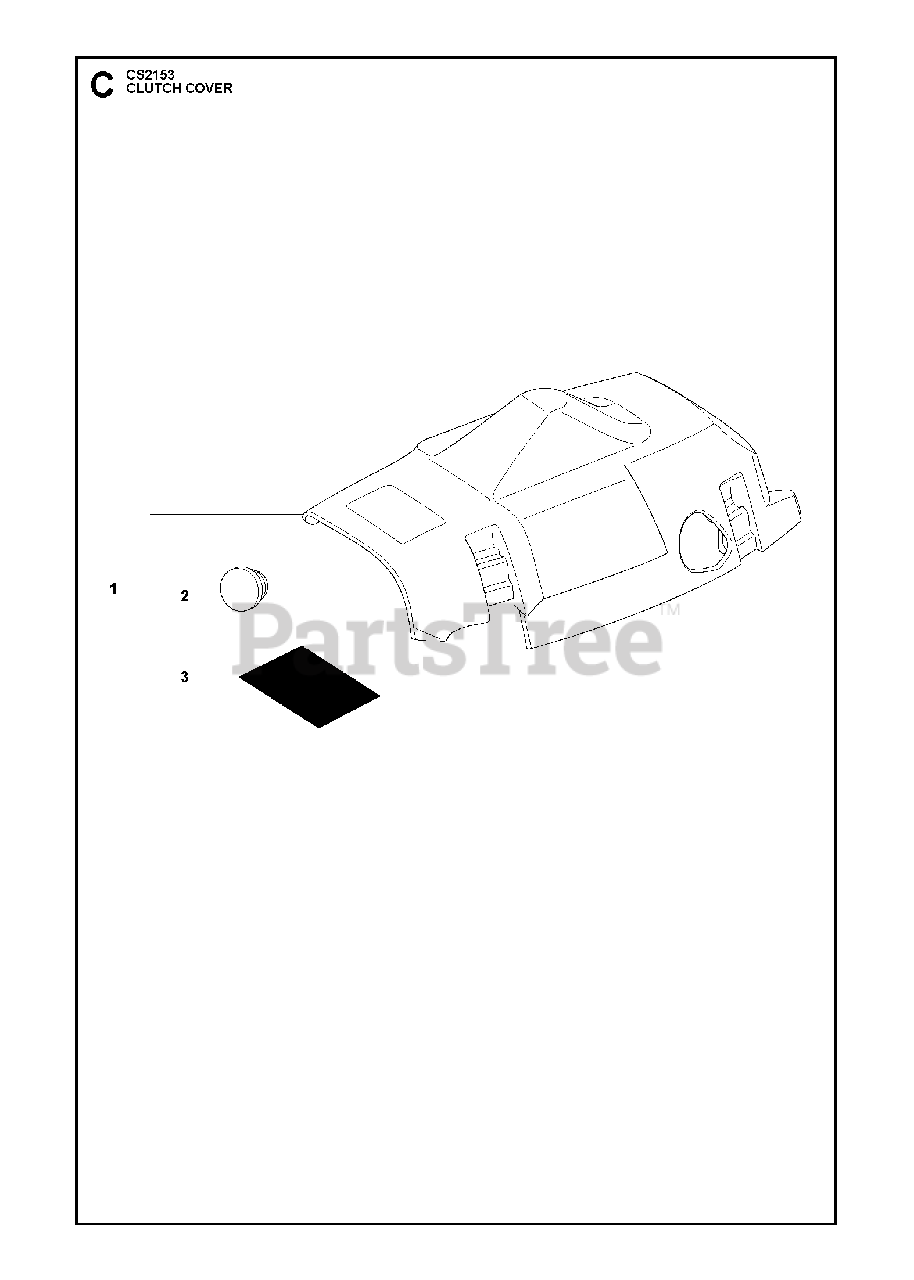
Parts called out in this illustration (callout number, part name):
1	CYLINDER COVER ASSY
2	PLUG
3	INSULATING FOIL/CYLINDER COVER
